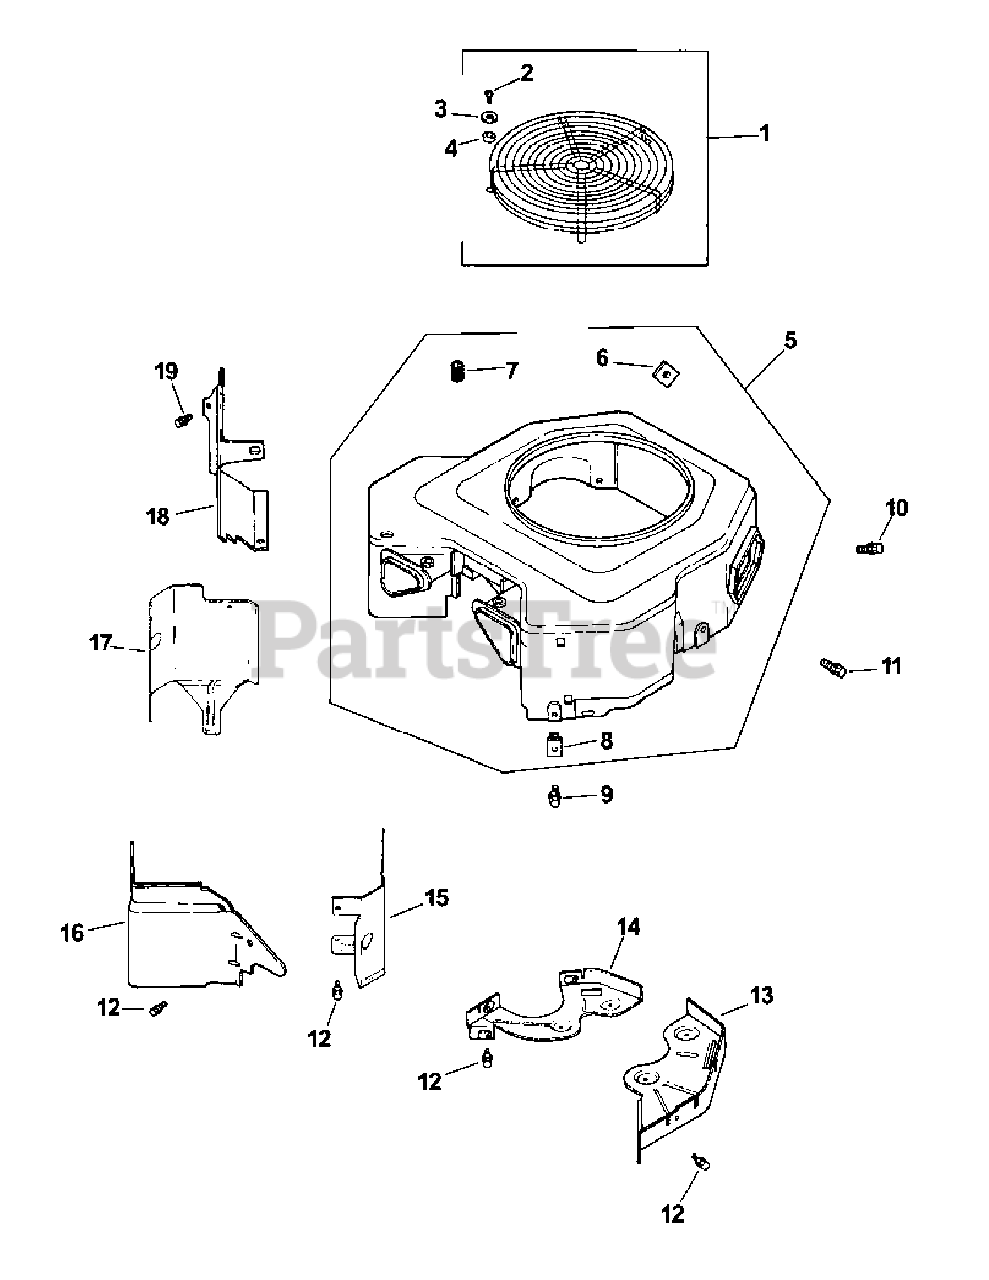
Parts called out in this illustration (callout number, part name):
2	Pan Head Screw
4	Spacer
5	Blower Housing
9	Hex Flange Screw
10	Hex Flange Screw
11	Hex Flange Screw
12	Hex Flange Screw
13	Backing Plate #2 Side
14	Backing Plate #1 Side
15	Cylinder Barrel Baffle #2 Side
16	Valley Baffle #2 Side
17	Cylinder Barrel Baffle #1 Side
18	Valley Baffle #1 Side
19	Hex Flange Screw
